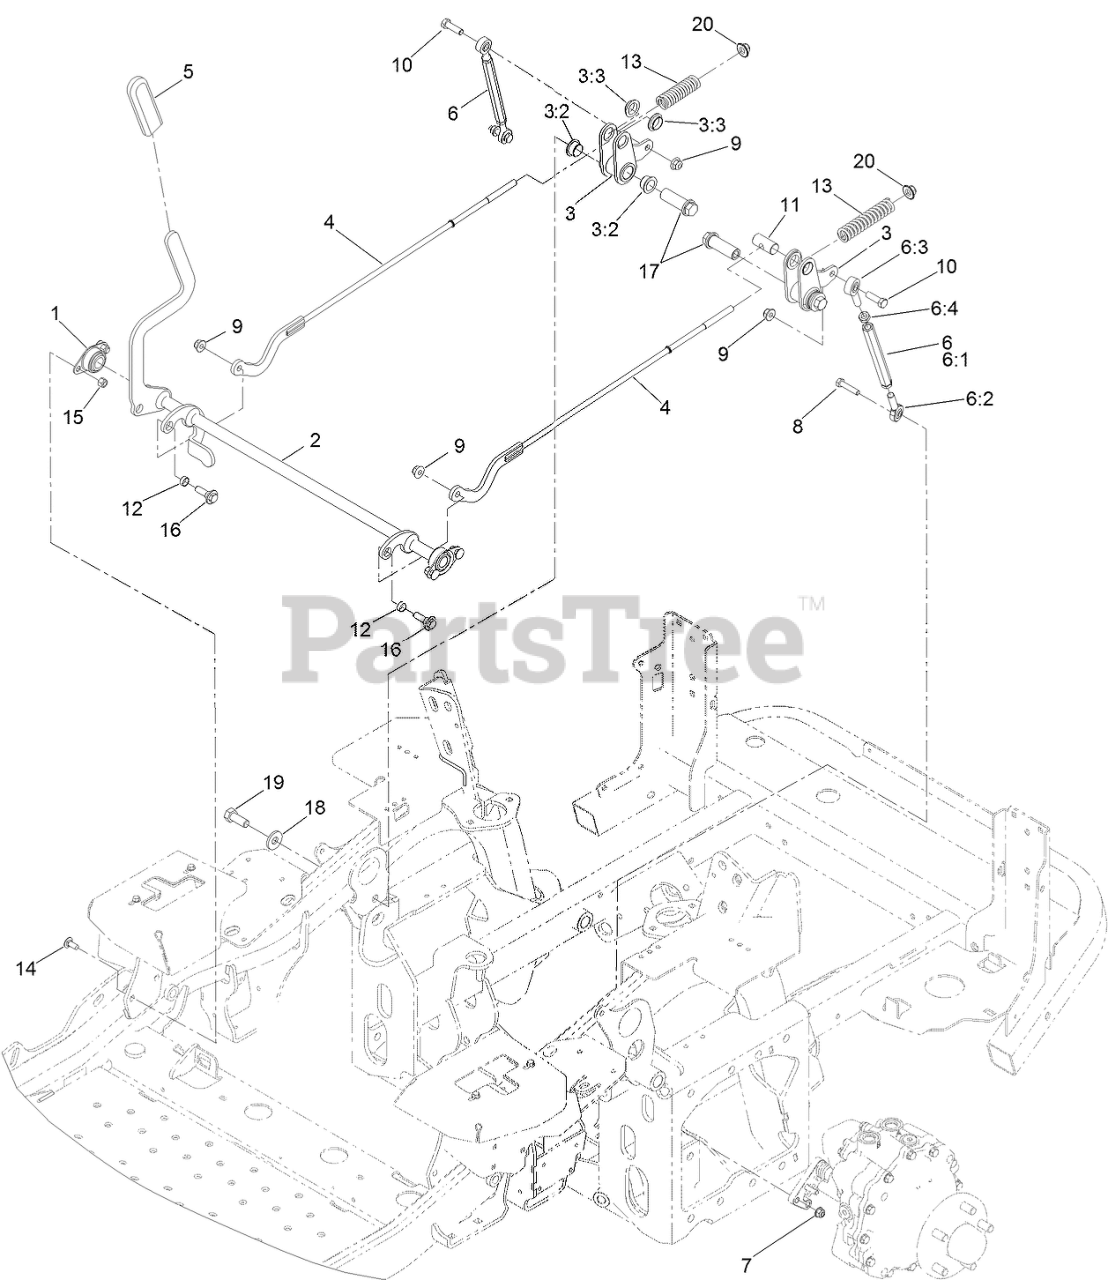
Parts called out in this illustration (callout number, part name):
1	BEARING-FLANGE, SIDE
2	SHAFT-BRAKE
3	BRAKE BELLCRANK ASM
3:2	BUSHING-FLANGE
3:3	BUSHING-FLANGE
4	LINK-BRAKE, UPPER
5	GRIP-LEVER
6	TURNBUCKLE ASM
6:1	TURNBUCKLE
6:2	BEARING-END, LH ROD
6:3	BALLJOINT
6:4	NUT-HJ
7	NUT-HF, NI
8	SCREW-HH
9	NUT-HF, NI
10	SCREW-HH
11	PIN-TRUNION
12	BEARING-SLEEVE
13	SPRING-COMPRESSION
14	SCREW-CARR
15	NUT-LOCK, NI
16	SCREW-SHOULDER, HWH
17	HUB-THREADED
18	WASHER-SPRING
19	SCREW-HH
20	Nut-Nyloc 3/8-16 Flg
